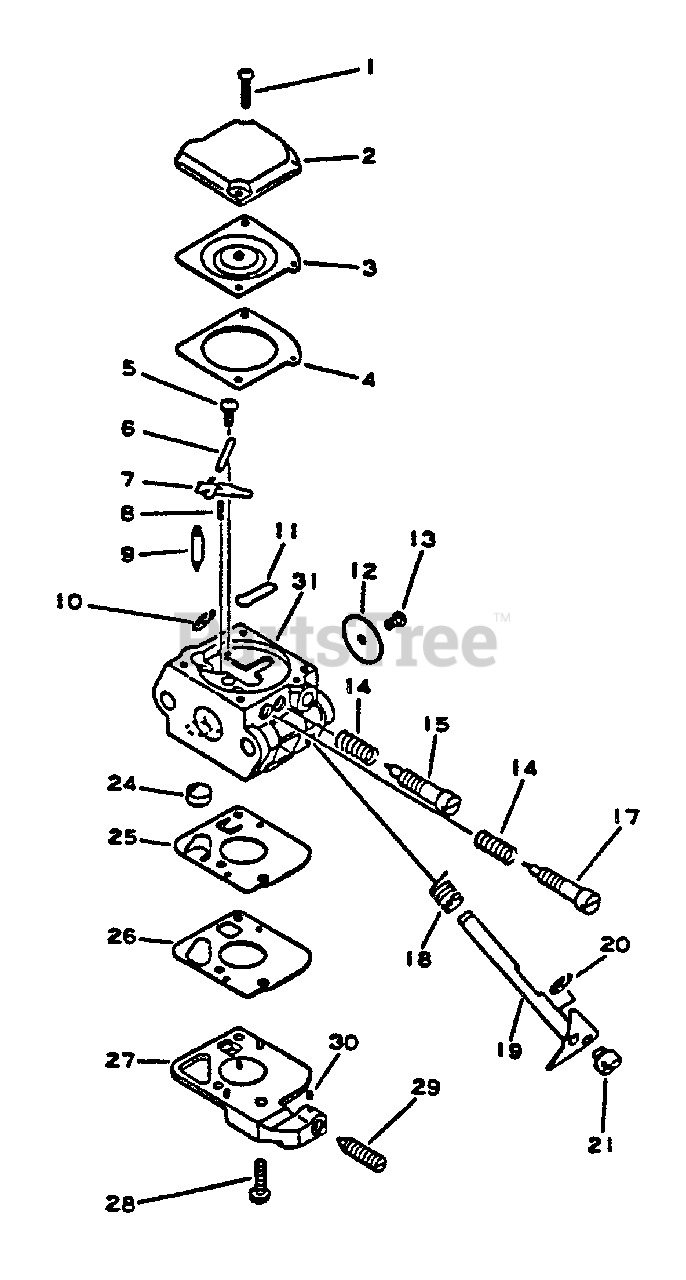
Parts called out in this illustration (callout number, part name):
2	COVER, METERING
3	DIAPHRAGM ASSY
4	GASKET, METERING
5	SCREW, METERING LEVER PIN
6	PIN, METERING LEVER
7	LEVER, METERING
8	SPRING
9	VALVE, NEEDLE
10	RING, RETAINING
11	PLUG, WELCH
12	VALVE, THROTTLE
13	SCREW
15	NEEDLE - HIGH SPEED
17	NEEDLE - LOW SPEED
18	SPRING, RETURN
19	SHAFT, THROTTLE
20	RING, RETAINING
24	STRAINER
25	DIAPHRAGM, PURGE
26	GASKET, PURGE
27	BASE, PURGE
28	SCREW, PUMP COVER
29	SCREW, IDLE ADJUST
30	PIECE, FRICTION
31	BODY, CARBURETOR
